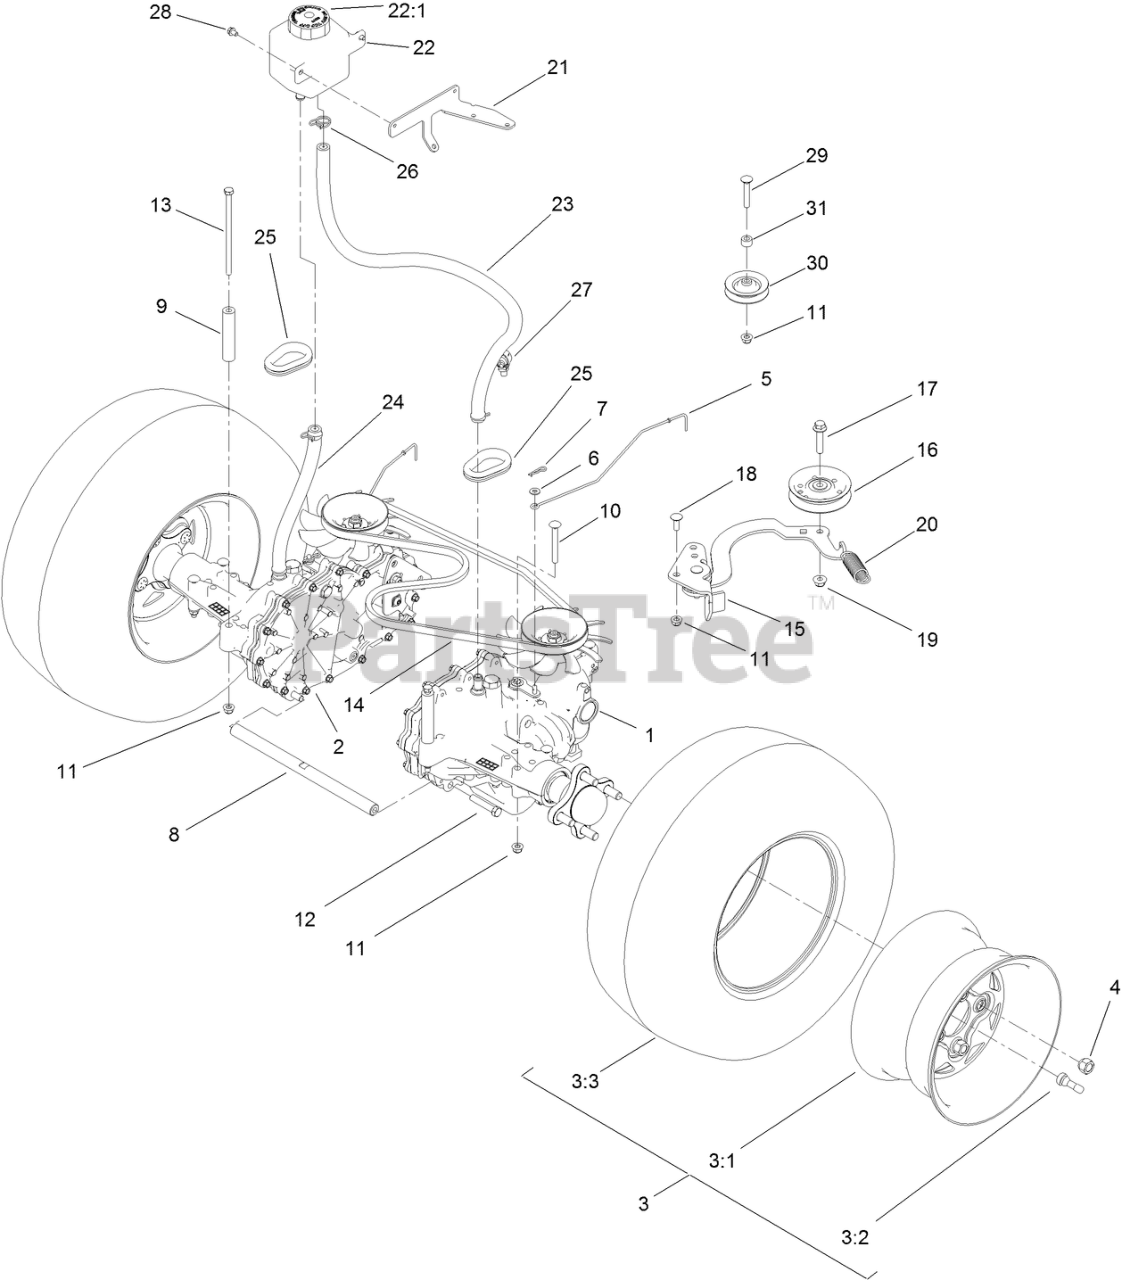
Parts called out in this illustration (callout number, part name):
1	TRANSMISSION, ZT-3100 LH
2	TRANSMISSION, ZT-3100 RH
3	WHEEL AND TIRE ASM
3:1	RIM-10"
4	NUT-LUG
5	ROD-BYPASS
6	WASHER-FLAT
7	PIN-COTTER
8	SHAFT-CROSS, HYDRO
9	SPACER - TRANSMISSION
10	SCREW-CARR
11	NUT-HF, NI
12	SCREW-HH W/LOCTITE
13	SCREW-HH
14	BELT-V
15	IDLER ARM ASM
16	PULLEY-IDLER, FLAT
17	SCREW-HHF
18	BOLT-CARR
19	NUT-HF, NI
20	SPRING-EXTENSION
21	BRACKET - EXPANSION TANK
22	TANK-HYD
22:1	CAP-RESERVOIR, HYD
23	HOSE-HYDRO
24	HOSE-OVERFLOW
25	GROMMET
26	CLAMP-HOSE
27	CLIP-TIE
28	SCREW-HWH
29	BOLT-CARR
30	PULLEY-IDLER
31	SPACER
